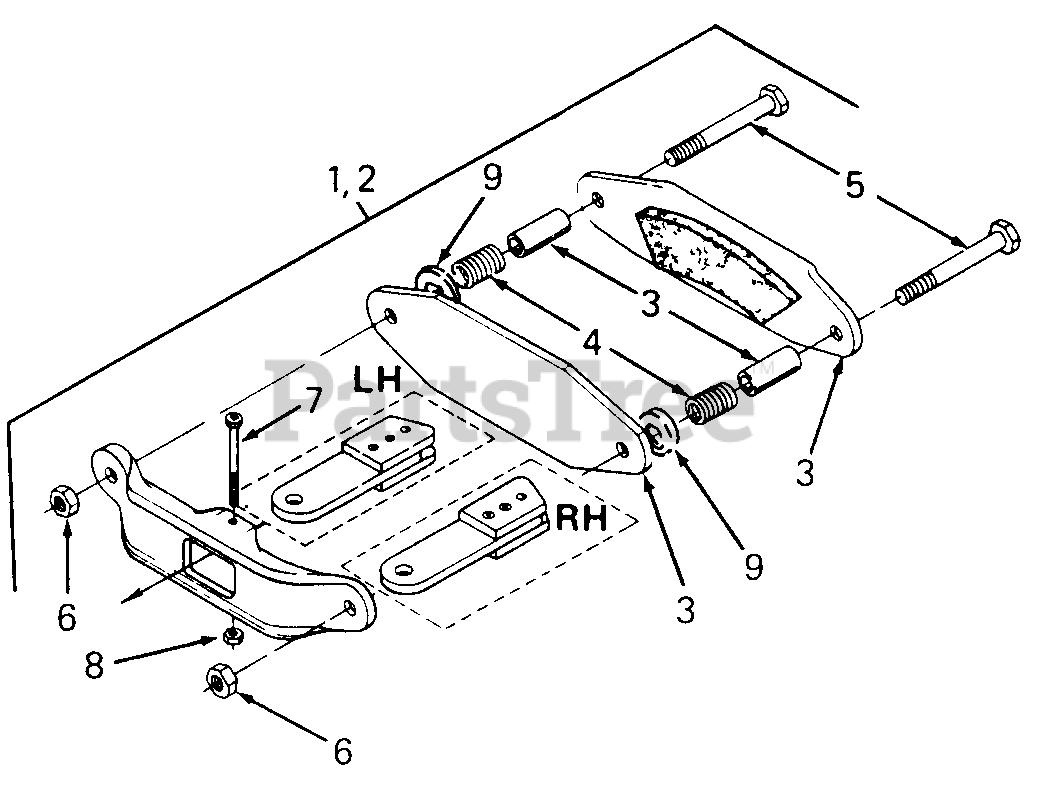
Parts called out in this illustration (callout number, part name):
1	Brake Kit, LH - Caliper
2	Brake Kit, RH - Caliper
3	Puck Kit, Brake
4	Spring, Compression
5	Screw, Hex Cap, 3/8-24 X 2.25 Lg
6	Nut, Hex Lock, 3/8-24
7	Screw, Socket Hd Shld, 5/16-18 X 1.25 Lg
8	Nut, Hex Top Lock Jam, 5/16-18 GR5
9	Washer, Flat, .390 X 1.0 X .030 Thk HDN
